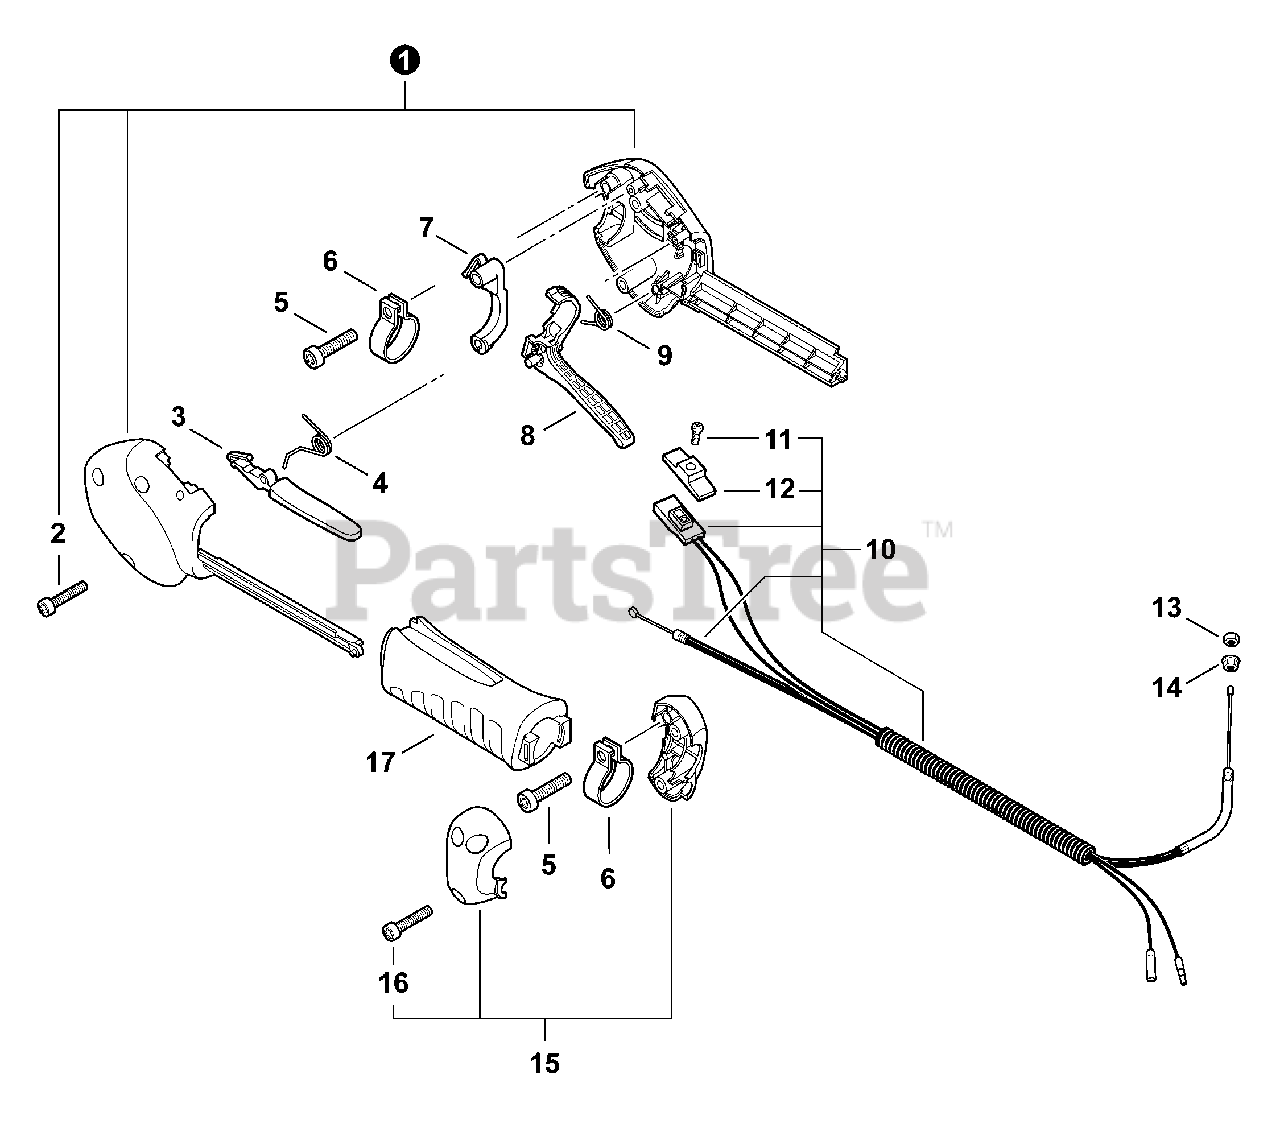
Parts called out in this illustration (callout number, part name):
1	CONTROL HANDLE KIT
2	SCREW - 4×20 -- TAPPING
3	LEVER, THROTTLE LOCKOUT
4	SPRING, LEVER RETURN
5	SCREW - 5×20
7	LOCKOUT, TRIGGER
8	TRIGGER, THROTTLE
9	SPRING, TRIGGER
10	CONTROL CABLE ASSY
11	SCREW - 3×10
12	KNOB, SWITCH - ORANGE
14	NUT - 6 -- FLANGE
15	HANDLE FIXTURE KIT
16	SCREW - 4×20 -- TAPPING
17	GRIP, HANDLE
